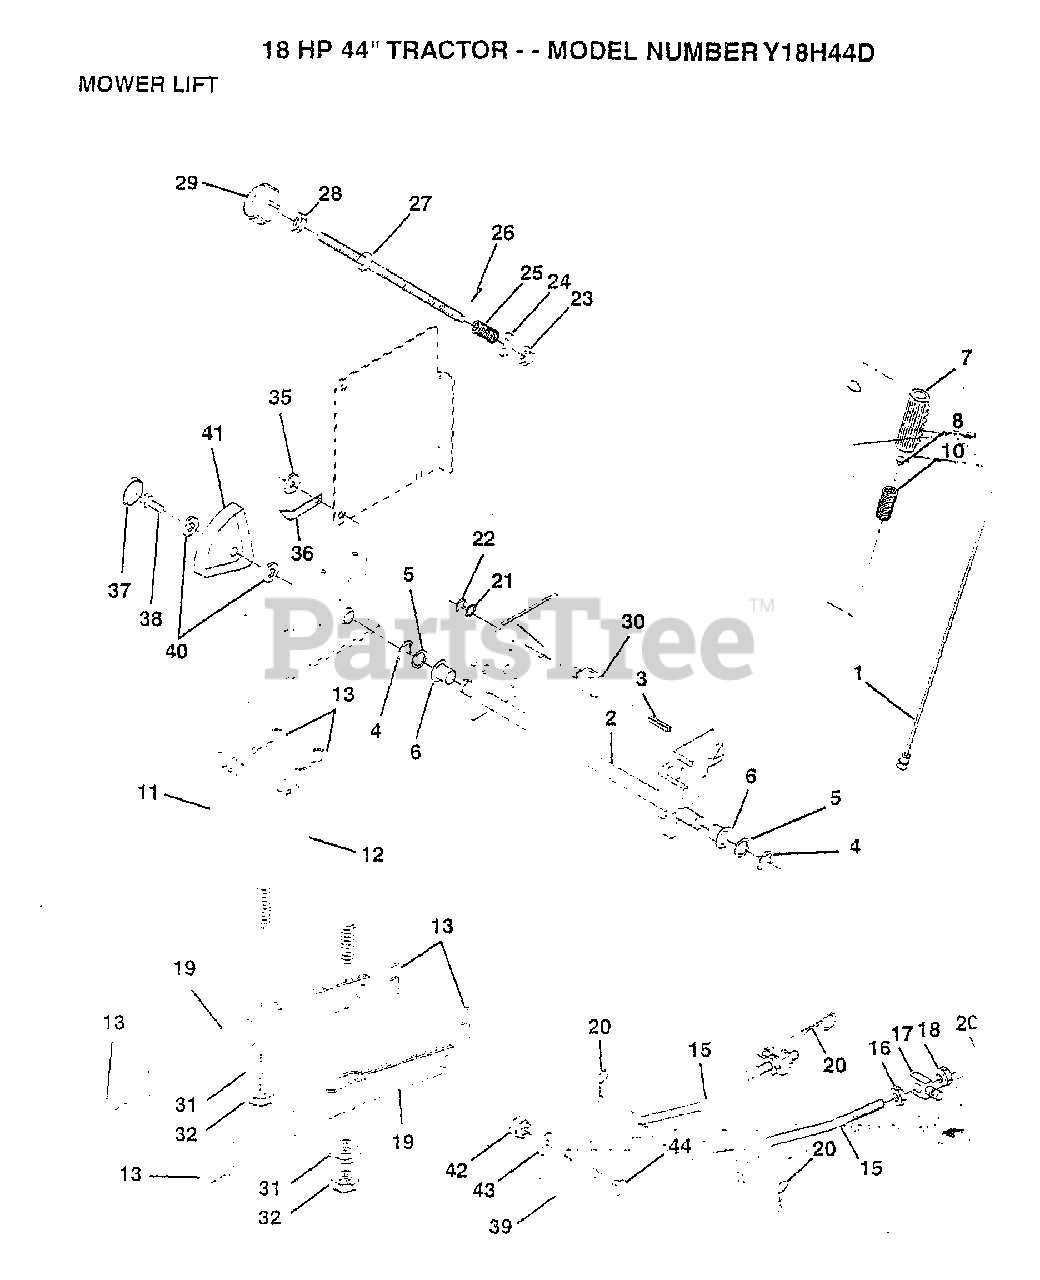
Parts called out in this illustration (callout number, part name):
1	WIRE.ASM.INNER
2	SHAFT.ASM.LIFT.RH
3	PIN GROOVE
5	WASHER
6	NYLON BEARING
7	GRIP
15	LINK.FRONT
16	NUT
17	TRUNION
18	NUT.LK.W/WSH.1/2.
19	ARM SUSP REAR
20	RETAINER.SPRING
21	WASHER
22	KLIP RING
23	NUT T
24	WASHER
25	SPRING T
27	ROD LIFT LT
28	NUT
29	KNOB INF 3/8-16
30	TRUNION LT
31	BEARING PVT LH
32	NUT.LOCK.3/8-24
35	WASHER T
36	POINTER HGT IND
37	"PLUG,HOLE"
38	SCREW
39	STOP.OVER.CENTER
40	WASHER
41	HEIGHT INDICATOR
42	NUT
43	WASHER GT
44	BOLT
